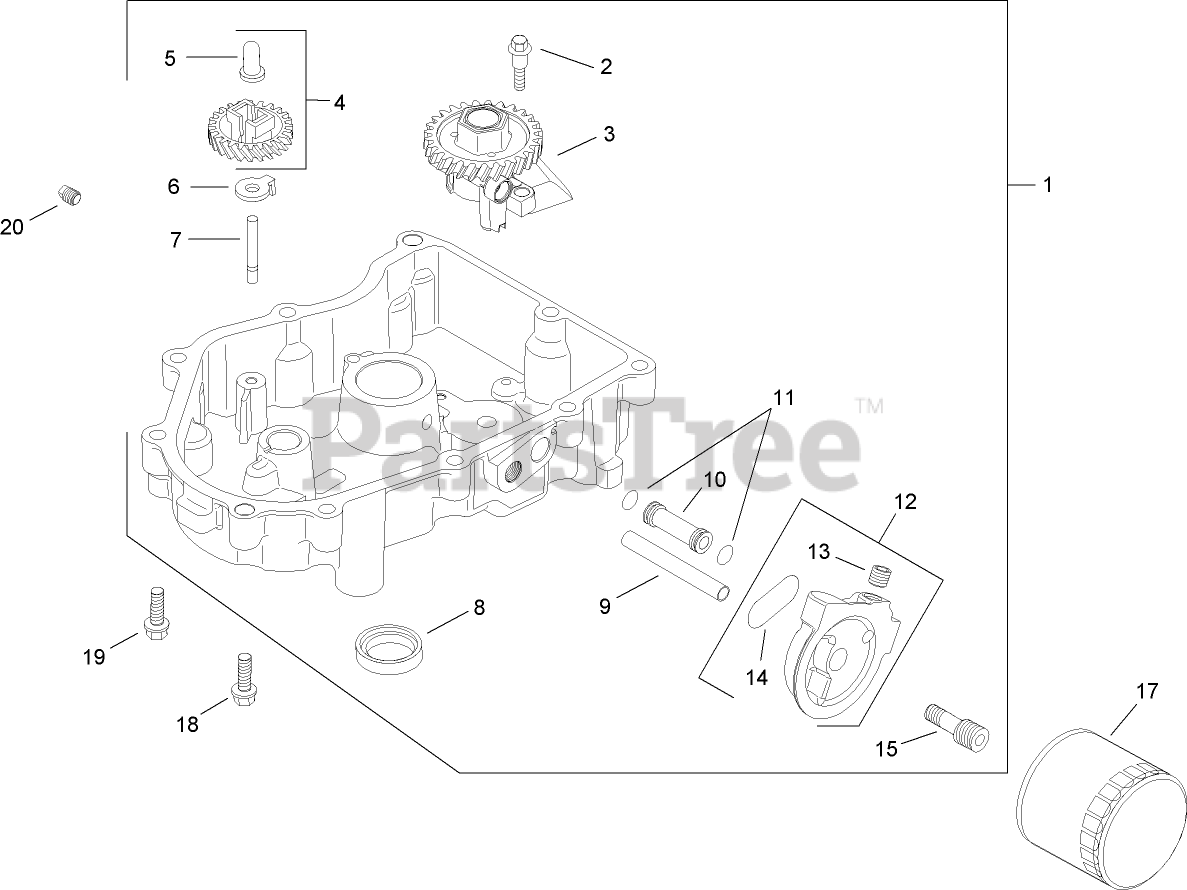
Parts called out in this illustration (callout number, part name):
1	Oil Pan ASM (Includes?2-15)
2	Screw-Hex Flange, Thread Forming (Shoulder)
3	Oil Pump ASM
4	Governor Gear Kit w/Pin (Includes?5)
5	Pin-Governor Regulating
6	Tab-Locking
7	Shaft-Governor Gear
8	Seal-Oil (PTO end)
9	Tube (Oil feed filter to oil pan)
10	Tube (Oil feed oil pan to filter)
11	O Ring
12	Adapter-Oil Filter (Includes?13-14)
13	Plug-Hex, Countersunk (1/8)
14	O Ring-Oil Filter Adapter
15	Nipple-Oil Filter
17	FILTER-OIL
18	Screw-Hex Flange (M8x1.25x45)
19	Screw-Hex Flange (M8x1.25x45)
20	Plug-Square Head, Solid (3/8)
